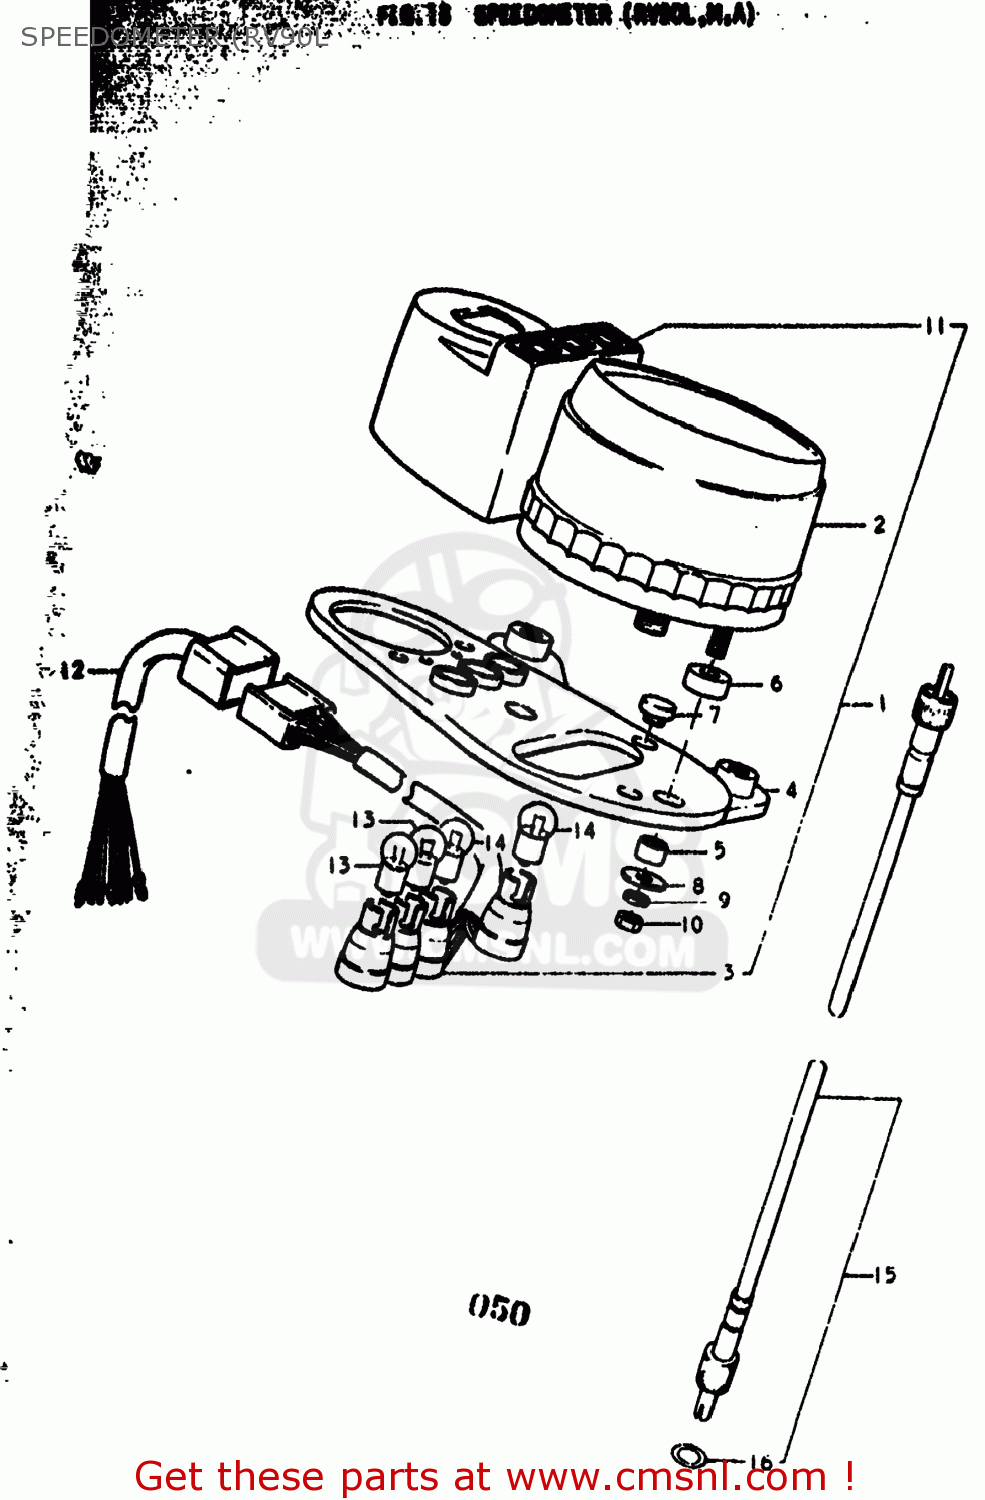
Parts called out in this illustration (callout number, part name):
1	SPEEDOMETER ASSEMBLY
2	SPEEDOMETER ASSEMBLY
3	SOCKET,METER
4	BRACKET,SPEEDOMETER
5	SPACER,METER
6	CUSHION,METER NO.1
7	CUSHION,METER
8	WASHER
9	LOCK WASHER
10	NUT
11	CASE,PILOT BULB
12	LEAD WIRE
13	BULB(6V1.7W,STANLEY,A61A)
14	BULB(6V/3W)
15	CABLE ASSY,SPEEDOMETER
16	OIL SEAL L,M,A,B
